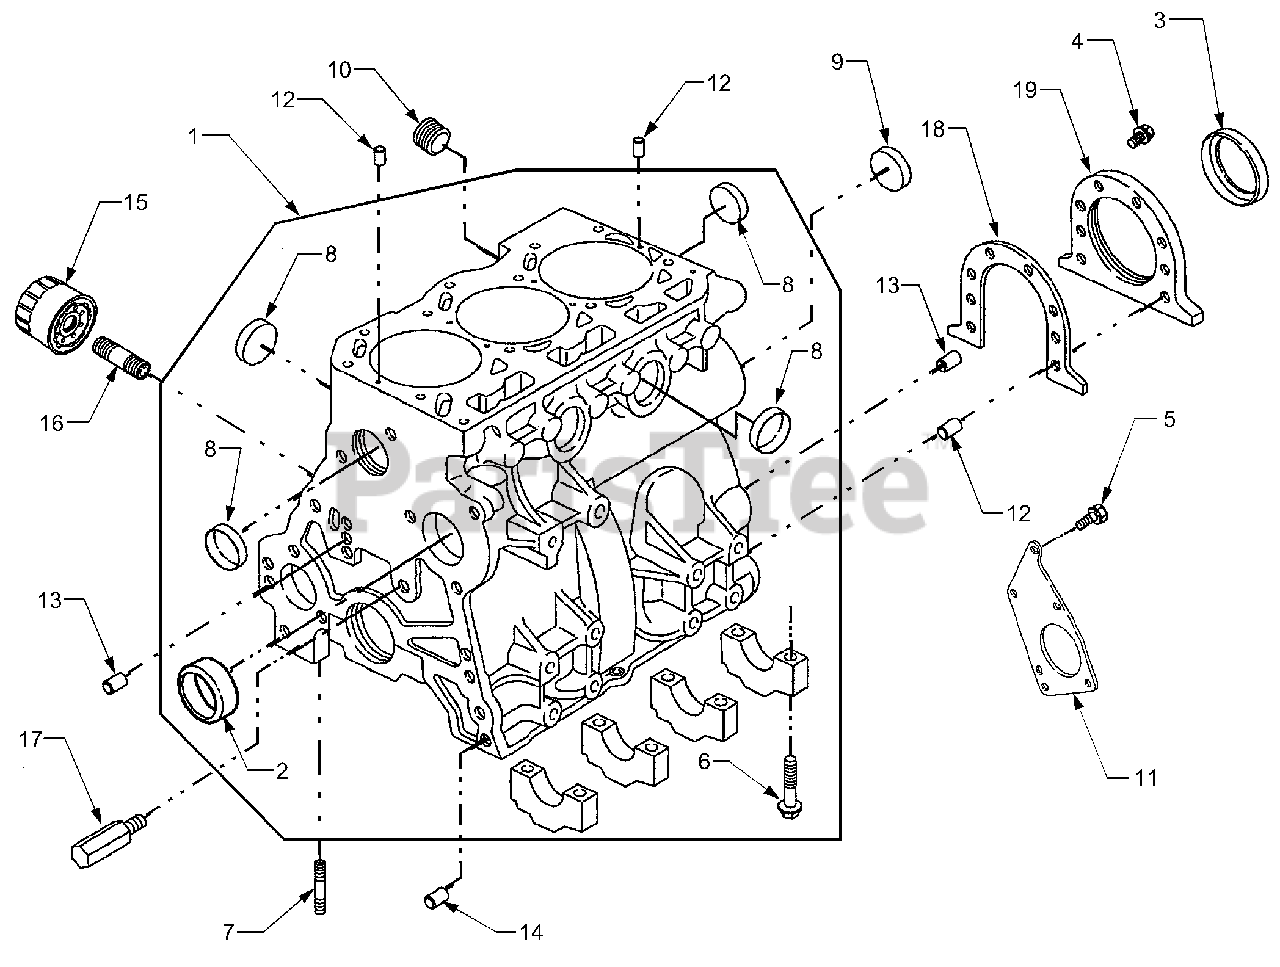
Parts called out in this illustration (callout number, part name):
1	Cylinder Assembly
2	Bushing
3	Seal, Oil
4	Screw, Hex, 6mm
5	Screw, Hex, 10mm
6	Screw, Hex, 10mm
7	Stud, Metric
8	Plug, Welch
9	Plug, Welch Camshaft
10	Plug, Cylinder Block
11	Bracket, Mounting
12	Pin, Locating
13	Pin, Locating
14	Pin, Locating
15	Filter, Oil
16	Adapter, Oil Filter
17	Nozzle, Oil
18	Gasket, Retainer
19	Seal, Retainer
